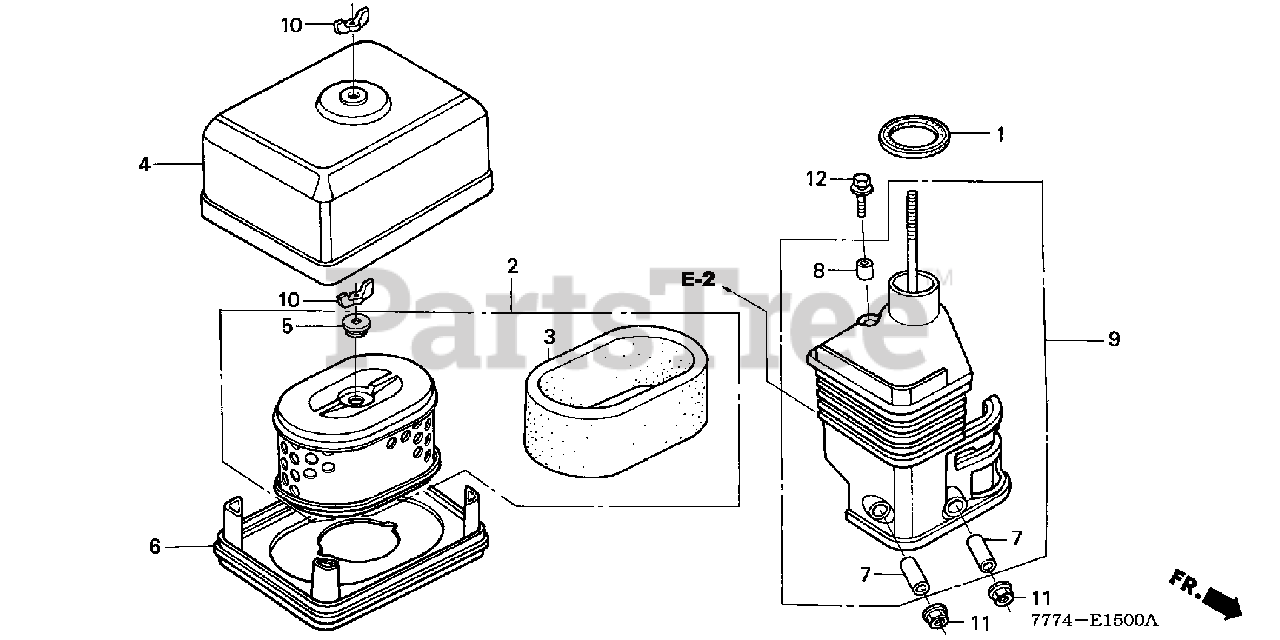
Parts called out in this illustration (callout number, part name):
1	GASKET, ELBOW
2	ELEMENT, AIR CLEANER (DUAL)
3	FILTER (OUTER)
4	COVER, AIR CLEANER (DUAL)
5	GROMMET, AIR CLEANER
6	NOSE, MUFFLER
7	COLLAR, AIR CLEANER
8	COLLAR B, AIR CLEANER
9	ELBOW, AIR CLEANER
10	NUT, TOOL BOX SETTING
11	NUT, FLANGE (6MM)
12	BOLT, FLANGE (6X20)
